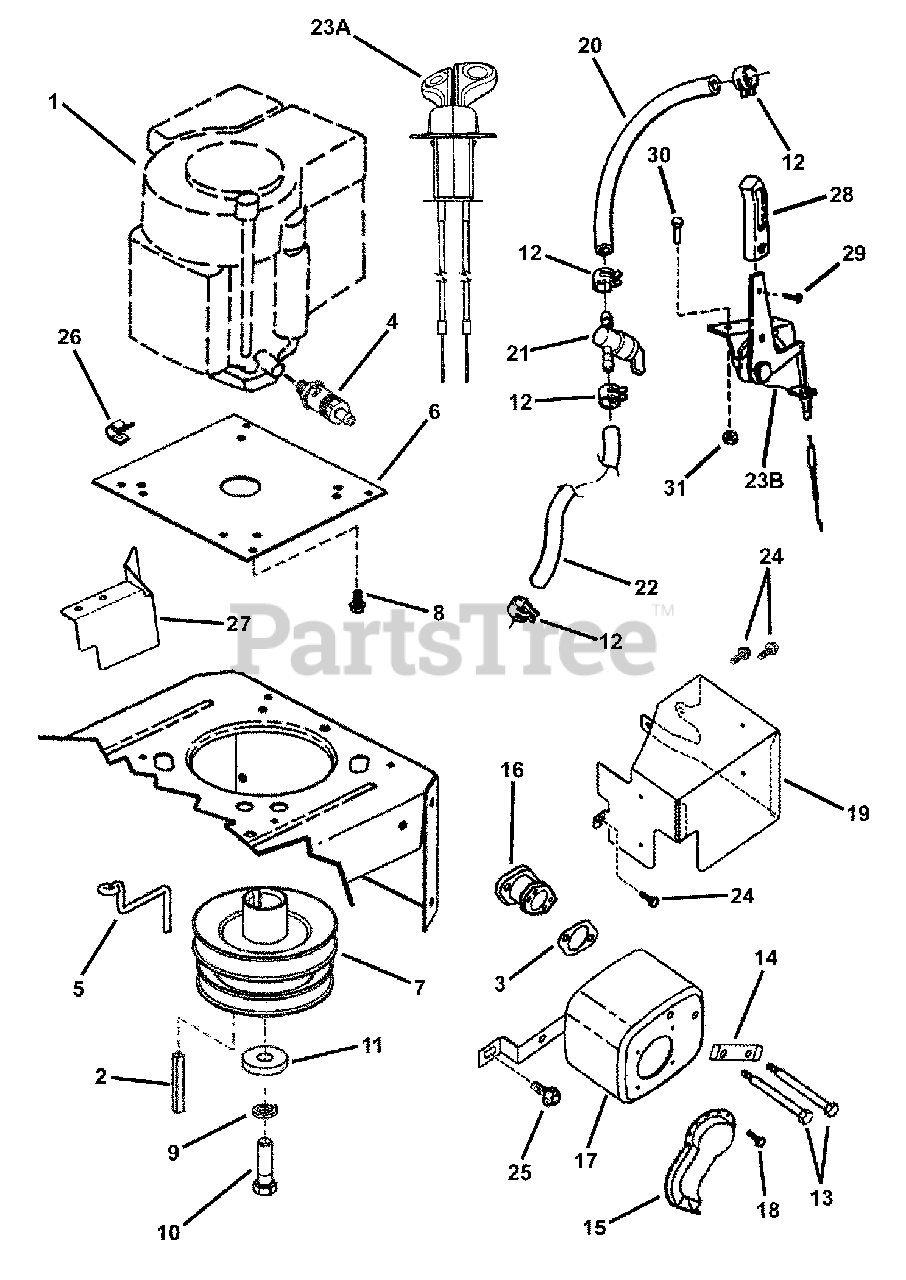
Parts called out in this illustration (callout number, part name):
1	ENGINE, 18 HP Briggs Intek
2	KEY, 1/4" Square x 2"
3	GASKET, Exhaust
4	ASSEMBLY, Oil Valve
5	GUIDE, Engine Belt
6	PLATE, Engine
7	PULLEY, Engine
8	SCREW, 3/8-16 x 1" Hex Washer Self-tap
9	WASHER, 7/16 Split Lock
10	SCREW, 7/16-20 x 1-1/2" Hex Head Cap, GR5
11	WASHER, .468 x 1.38 x .25 Flat (special)
12	HOSE CLAMP, .490 x .31
13	BOLT, 5/16-18 x 4" Shoulder
14	SCREW LOCK
15	DEFLECTOR, Muffler
16	ADAPTER, Muffler
17	MUFFLER, 14.5HP B&S Engine
18	SCREW, #8-18 x 1/2" Hex Head Sheet Metal
19	HEAT SHIELD, Muffler- 17HP B&S Intek
20	HOSE, Fuel, 1/4 I.D. x 14" long
21	VALVE, Fuel
22	HOSE, Fuel, 12-1/2" long
23A	CONTROL, Throttle/Choke, Dual Lever
23B	CONTROL, Throttle
24	SCREW, 1/4-20 x 1/2" Hex Washer Self-Tap
25	BOLT, 5/16-18 x 5/8" Hex Flange Lock, GR5
26	HARNESS CLIP (vinyl covered)
27	HEAT SHIELD
28	LEVER, Throttle Control
29	RIVET, Plastic Snap
30	SCREW, #10-32 x 5/8" Hex Washer Head Machine
31	NUT, #10-32 Hex Nyloc
